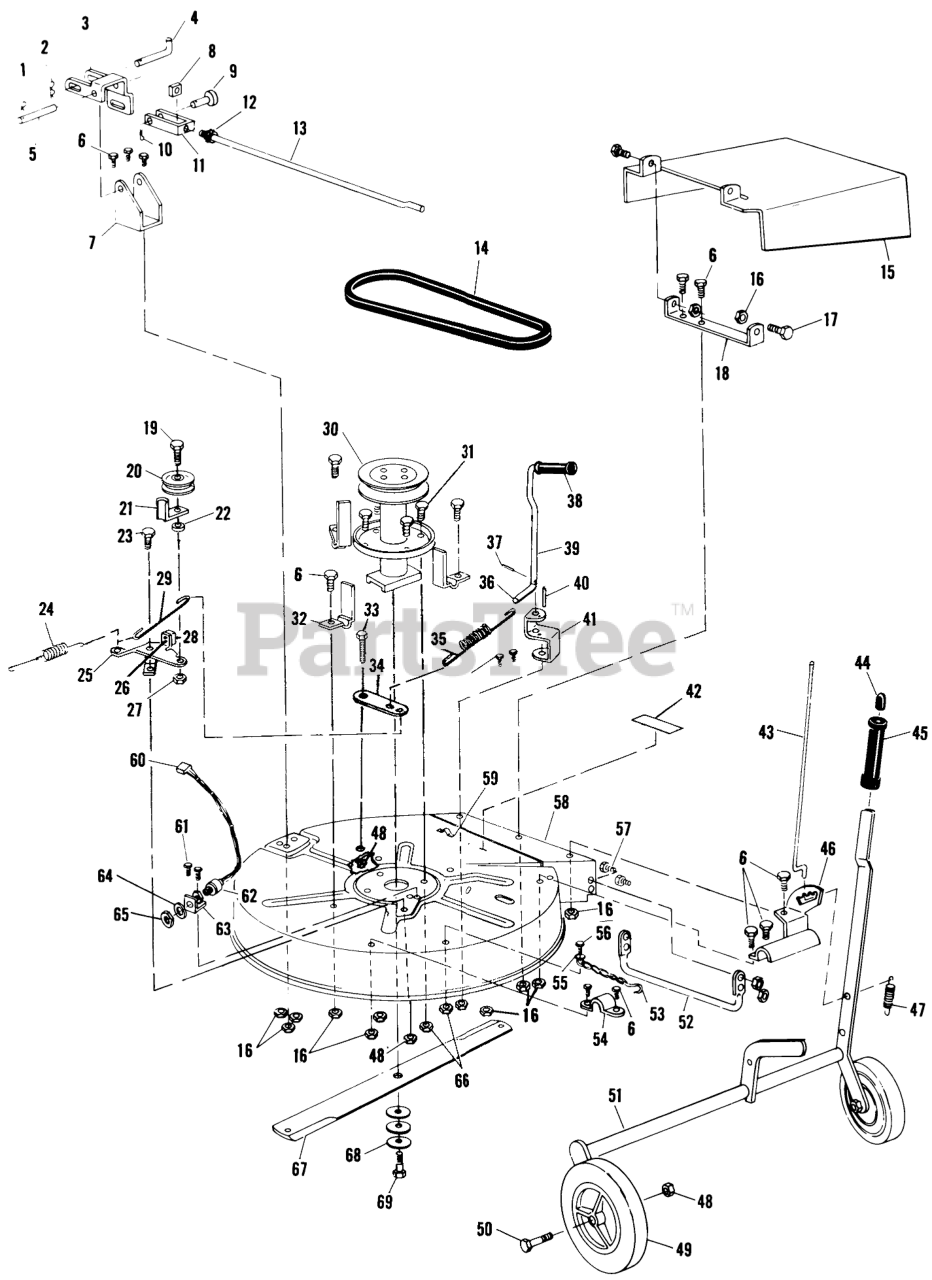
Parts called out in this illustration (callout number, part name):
1	Pin-cotter 3/32 X 1/2
2	Hairpin Cotter
3	Lifting Yoke
4	Washer
5	Pin, Level Control
6	Screw, Hex Hd, 5/16-18 x 5/8 In.
7	Pivot Bracket
8	Nut
10	Hairpin
11	Clevis
12	Nut, Hex, 1/4-20 Thd
13	Rod, Level Control
14	V-Belt 4L-52.5
15	Chute Deflector
16	Nut-Nylok
17	Shoulder Bolt
18	Bracket, Chute Deflector Pivot
19	Bolt Hex 3/8-16
20	Idler Pulley
21	Arm, Idler
22	Spacer
23	Shoulder Bolt
24	Spring, Brake
25	Blade Idler Arm Assembly Includes Items 26 & 28)
26	Rivet
27	Nut-Jam 3/8-16
28	Pad Brake
29	Rod, Engagement
30	Quill Assembly
31	SCREW-HWH, THREAD CUT
32	Deck Belt Guide
33	Idler Stud
34	Bell Crank Assembly
35	Spring, Blade Idler & Rod Assy
36	Lever, Lower Blade Throwout
37	Roll Pin, 1/8 x 9/16 In.
38	Hand Grip
39	Clip-Wire
40	SPIROL PIN
41	Bracket, Blade Throwout
42	Decal, Mower Deck
43	Control Rod, Quadrant
44	Thumb Button
45	Hand Grip
46	Quadrant, Height Adjust
47	Spring, Height Control Rod
48	Nut
49	Wheel & Tire Assembly
50	Shoulder Bolt
51	Support Shaft Assembly
52	Chute Guard
53	Safety Chain Assembly
54	"U" Bracket
55	Flatwasher, 1/4 In.
56	Bolt 1/4-20 X 3/4
57	Bolt-1/4-20 x 5/8
58	Mower Deck
59	Press Clip
60	Wire Assembly, Deck
61	Bolt, 1/4-x 1/2
62	Safety Switch
63	Bracket, Safety Switch
64	Lockwasher (Switch Part)
65	Nut (Switch Part)
66	Nut-Nylok
67	Blade, 30 In.
68	Spring Washer
69	Bolt-Nylok 3/8-24 x 1
96	Service Rod (Not Illust.)
